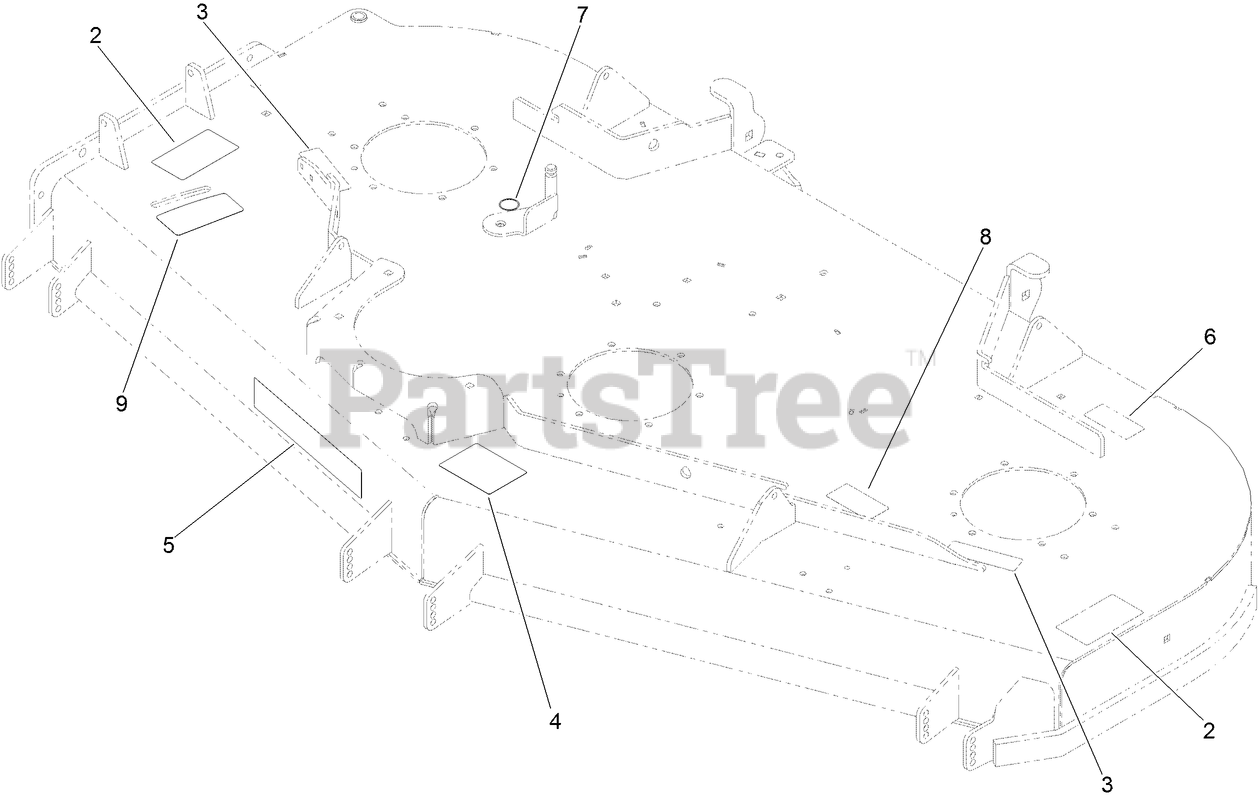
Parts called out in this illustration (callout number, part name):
2	DECAL-DANGER THROWN OBJECTS
3	DECAL-COVER, MISSING
4	DECAL-SCALP, ANTI
6	DECAL-BOLT TORQUE
7	DECAL-GREASE
8	DECAL-BELT ROUTING
9	DECAL-ADJUSTMENT, BAFFLE
